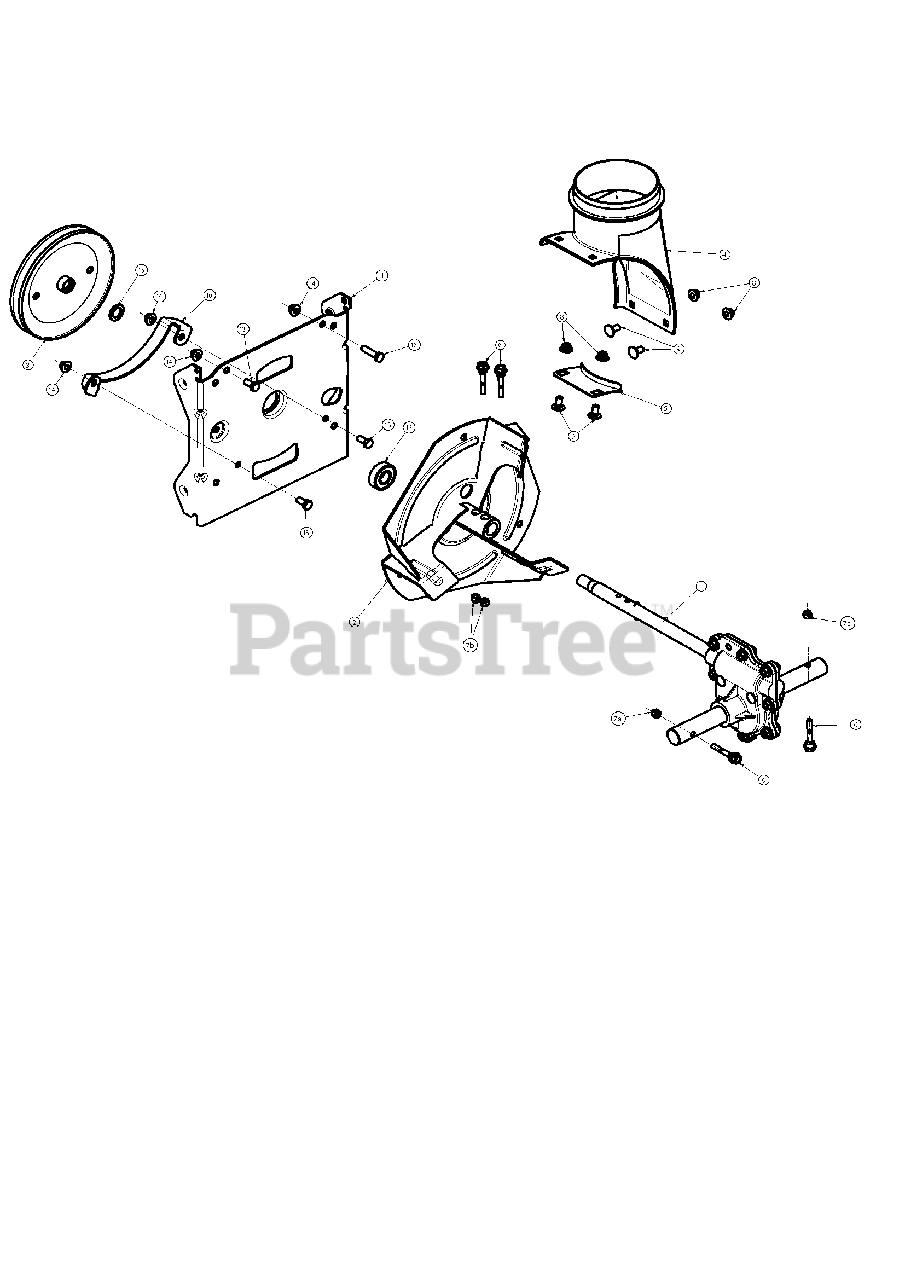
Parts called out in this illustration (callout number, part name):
1	Gear Box Assembly Alum
2	Impeller, Steel Snow Black
3	Screw-on Pulley, 7.3
4	Discharge Chute Base
5	BRACKET, CORNER DISCHARGE
6	Hex Head Shear Bolt, 1/4-20 X 1-13/16
7	LOCKNUT
8	Flange Hex Nut, Nylock Blk 5.16-1
9	Carriage Wafer Bolt, 5/16-18
10	BRACKET.BELT.KEEPER.LOWER.BLAC
11	Auger Housing Inter Bracket, Black
13	BOLT, HEX HEAD 5/16-18
14	NUTNYLOK.FLRANGE.5/16-18
15	Impeller Pulley Washer
16	BOLT.5/16-18X1-1/4 FULL THD
